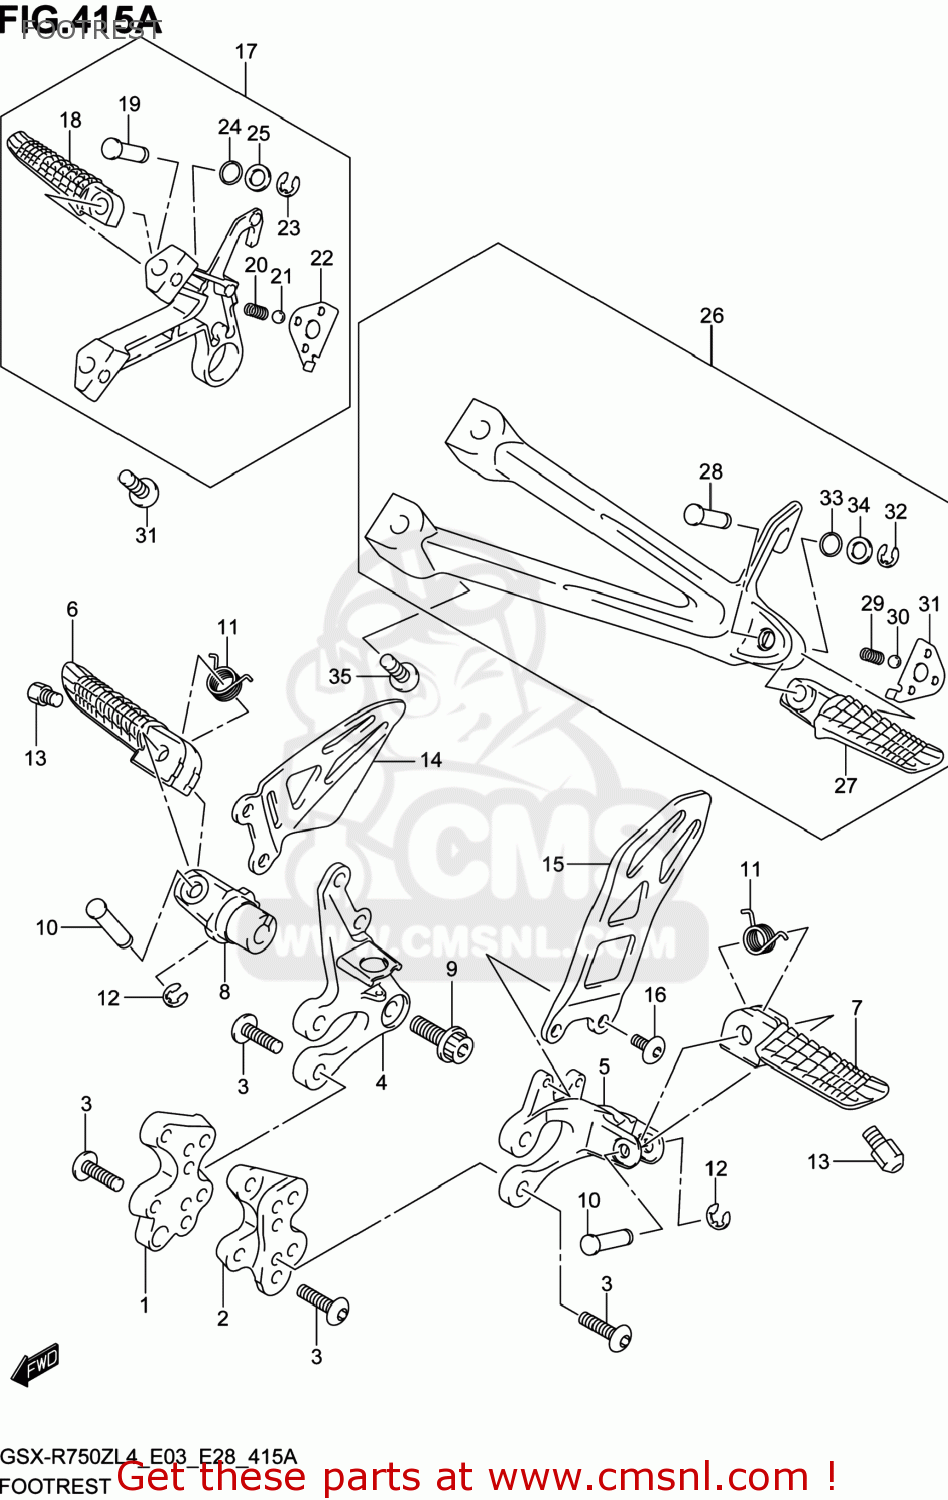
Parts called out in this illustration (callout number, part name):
1	BRACKET,FR FOOTREST NO.1,R
2	BRACKET,FR FOOTREST NO.1,L
3	BOLT(8X23)
4	BRACKET,FR FOOTREST NO.2,R
5	BRACKET,FR FOOTREST NO.2,L
6	BAR,FR FOOTREST,R
7	BAR,FR FOOTREST,L
8	HOLDER,FOOTREST
9	BOLT(10X28)
10	PIN
11	SPRING
12	E RING
13	BOLT,BANK SENSOR
14	GUARD,FR FOOTREST,R
15	GUARD,FR FOOTREST,L
16	SCREW,FOOTREST GUARD,L
17	FOOTREST ASSY,PILLION,R
18	BAR,PILLION FOOTREST,R
19	PIN
20	SPRING
21	BALL
22	PLATE,PILLION FOOTREST,R
23	E RING
24	O RING(D:2.4,ID:6.9)
25	WASHER(8.5X14X1.0)
26	FOOTREST ASSY,PILLION,L
27	BAR,PILLION FOOTREST,L
28	PIN
29	SPRING
30	BALL
31	PLATE,PILLION FOOTREST,L
32	E RING
33	O RING(D:2.4,ID:6.9)
34	WASHER(8.5X14X1.0)
35	BOLT(8X23)
